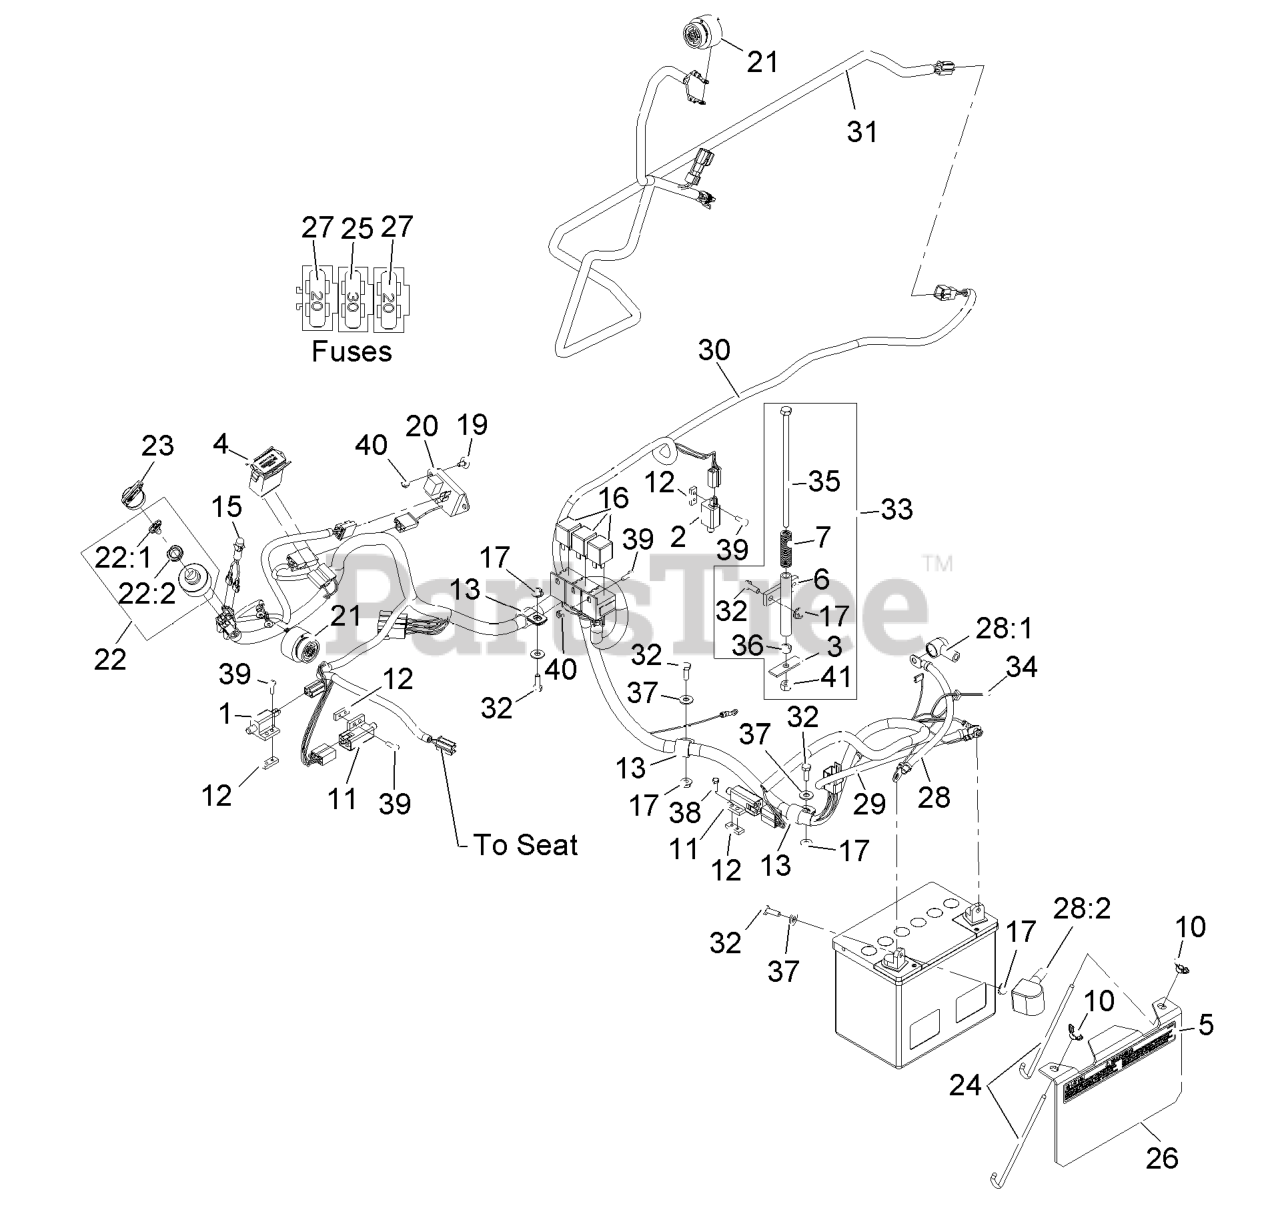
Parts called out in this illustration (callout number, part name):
1	SWITCH-OPEN, NORMALLY
2	SWITCH-CLOSED, NORMALLY
3	PLATE-SWITCH, SEAT
4	METER-HOUR
5	DECAL-BATTERY
6	MOUNT-SPRING, SEAT
7	SPRING-SWITCH, SEAT
10	WINGNUT
12	PLATE-TAPPED
13	CLIP-LOOM
15	INDICATOR-LED, RED
19	BOLT-CARR
20	MODULE-DELAY, SEAT
21	ALARM-TONE, DUAL
22	ASM,SWITCH W/NUT
22:1	KEYS-IGNITION (SPARE PAIR
22:2	NUT-SWITCH, IGNITION
23	KEY-IGNITION
24	BOLT-HOLDDOWN
25	FUSE-BLADE TYPE, 30 AMP
27	FUSE-BLADE TYPE, 20 AMP
28	CABLE-BATTERY, POSITIVE
28:1	INSULATOR-SOLENOID
28:2	INSULATOR-BATTERY
29	CABLE-BATTERY, NEGATIVE
31	HARNESS-WIRE, HOPPER
32	SCREW-HH
33	HOPPER SWITCH ACTUATOR AS
34	TIE-CABLE
35	SCREW-HH
36	NUT-HEX
37	WASHER-FLAT
39	SCREW-PPH
40	NUT-LOCK, NI
41	NUT-LOCK, NI
